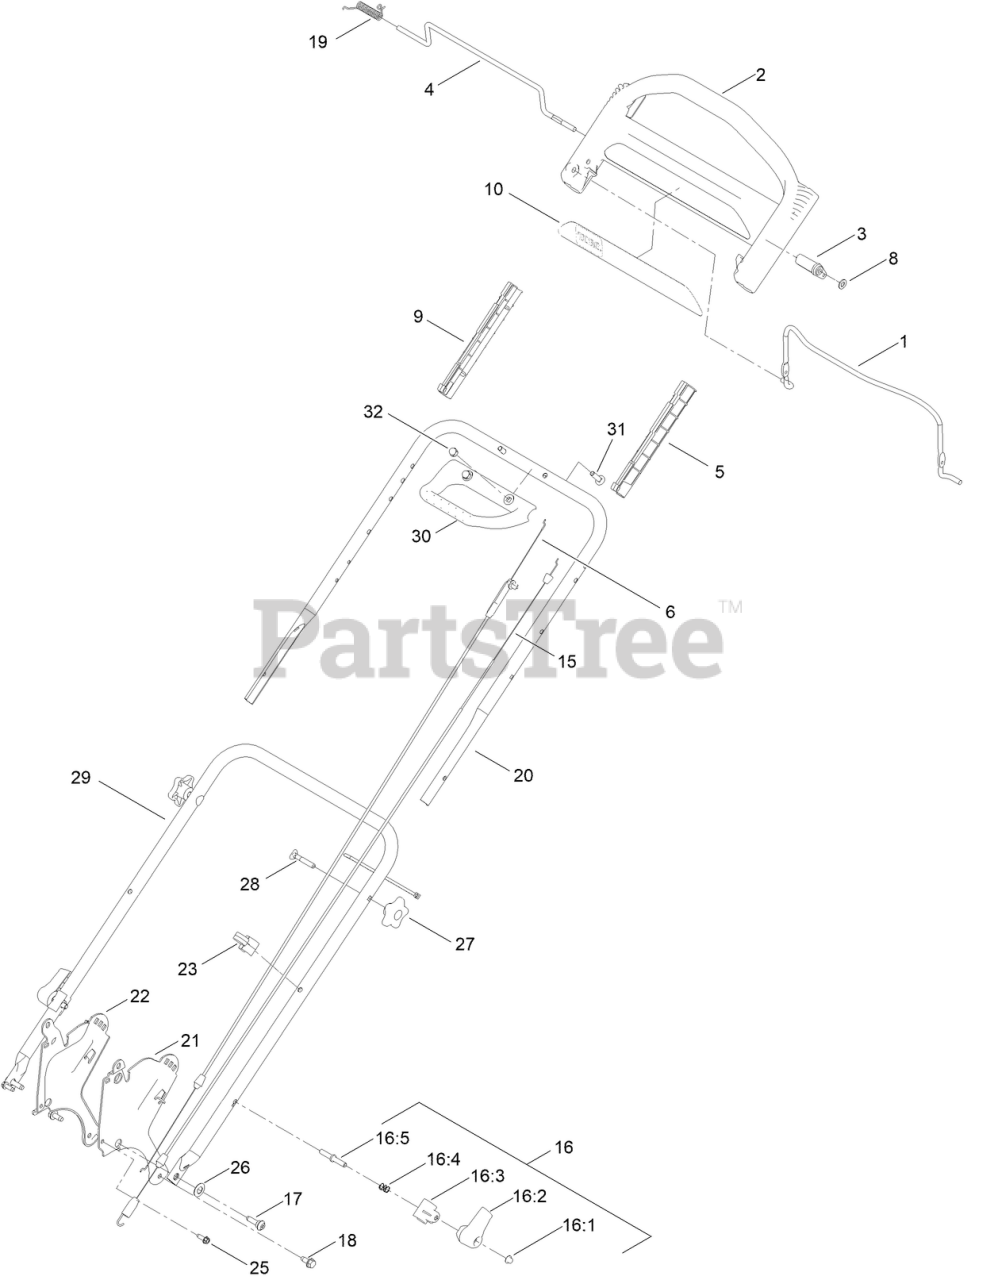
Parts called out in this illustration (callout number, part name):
1	BAIL-BRAKE
2	HANDLE-CONTROL
3	LEVER-TRACTION
4	BAR-CONTROL, TRACTION
5	GUIDE-LH
6	CABLE-BRAKE
8	WASHER-PLAIN
9	GUIDE-RH
10	DECAL-HANDLE
15	CABLE-TRACTION
16	QUICK RELEASE ASM
16:1	NUT-PUSH
16:2	LEVER-RELEASE
16:3	ANCHOR-SPRING
16:4	SPRING-COMPRESSION
16:5	ROD-RELEASE
17	SCREW-SHOULDER, BHTF
18	SCREW-HWHTF
19	SPRING-TORSION
20	HANDLE-UPPER
21	BRACKET-HANDLE, LH
22	BRACKET-HANDLE, RH
23	GUIDE-CABLE
25	SCREW-HWHTF
26	WASHER-SPRING, CONICAL
27	KNOB-HANDLE
28	SCREW-HANDLE
29	HANDLE-LOWER
30	HANDLE-ASSIST, TRACTION
31	BOLT-CARRIAGE
32	NUT-ACORN
